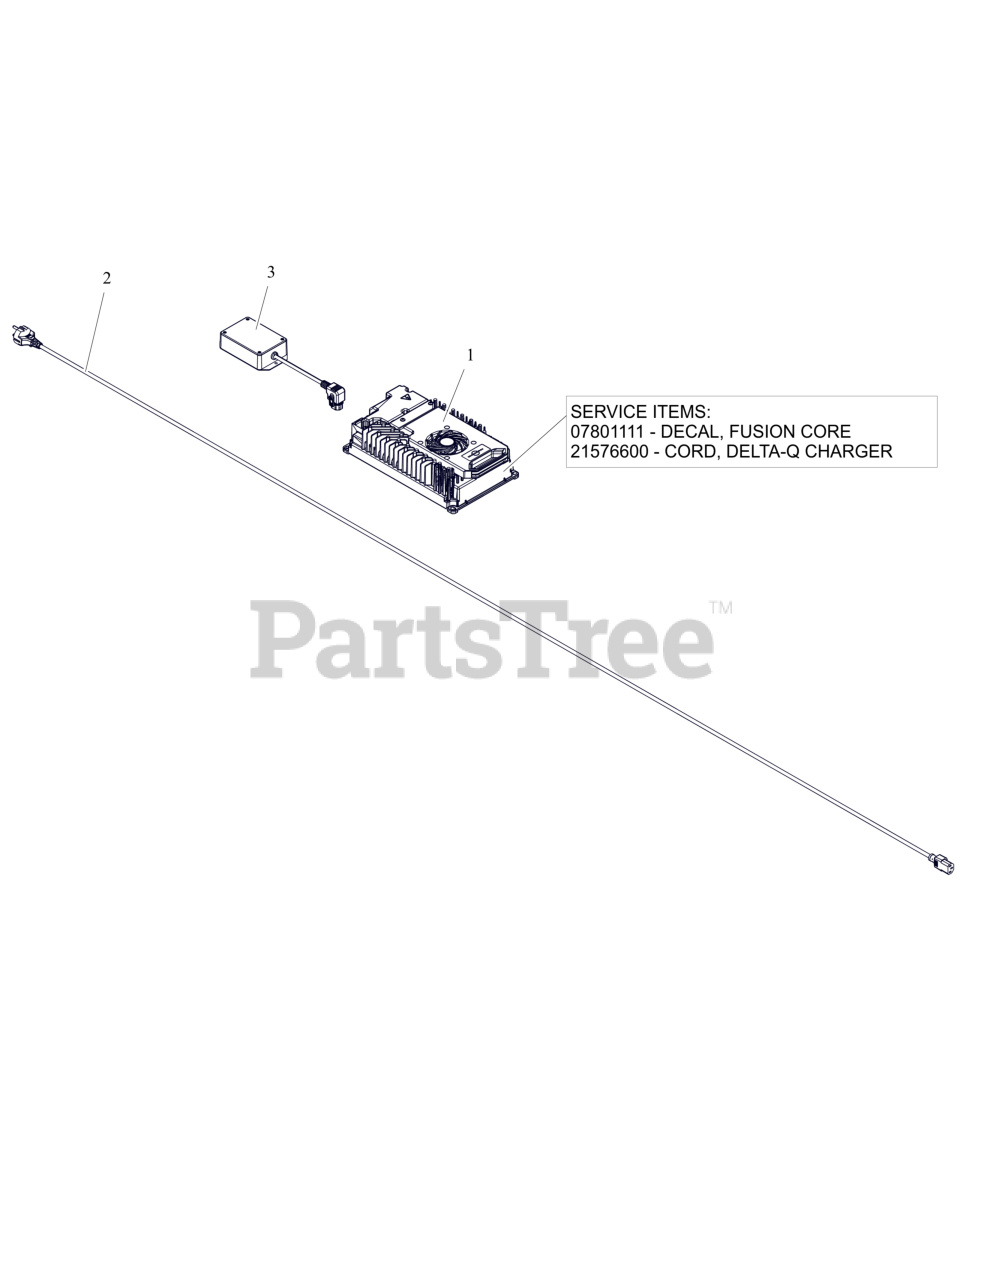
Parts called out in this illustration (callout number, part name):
1	CHARGER, BATTERY DELTA-Q
1	DECAL, FUSION CORE
1	CORD, DELTA-Q CHARGER
2	CORD, POWER EU 220V AC
3	FILTER ,EMI, 120/250V,50-60HZ
